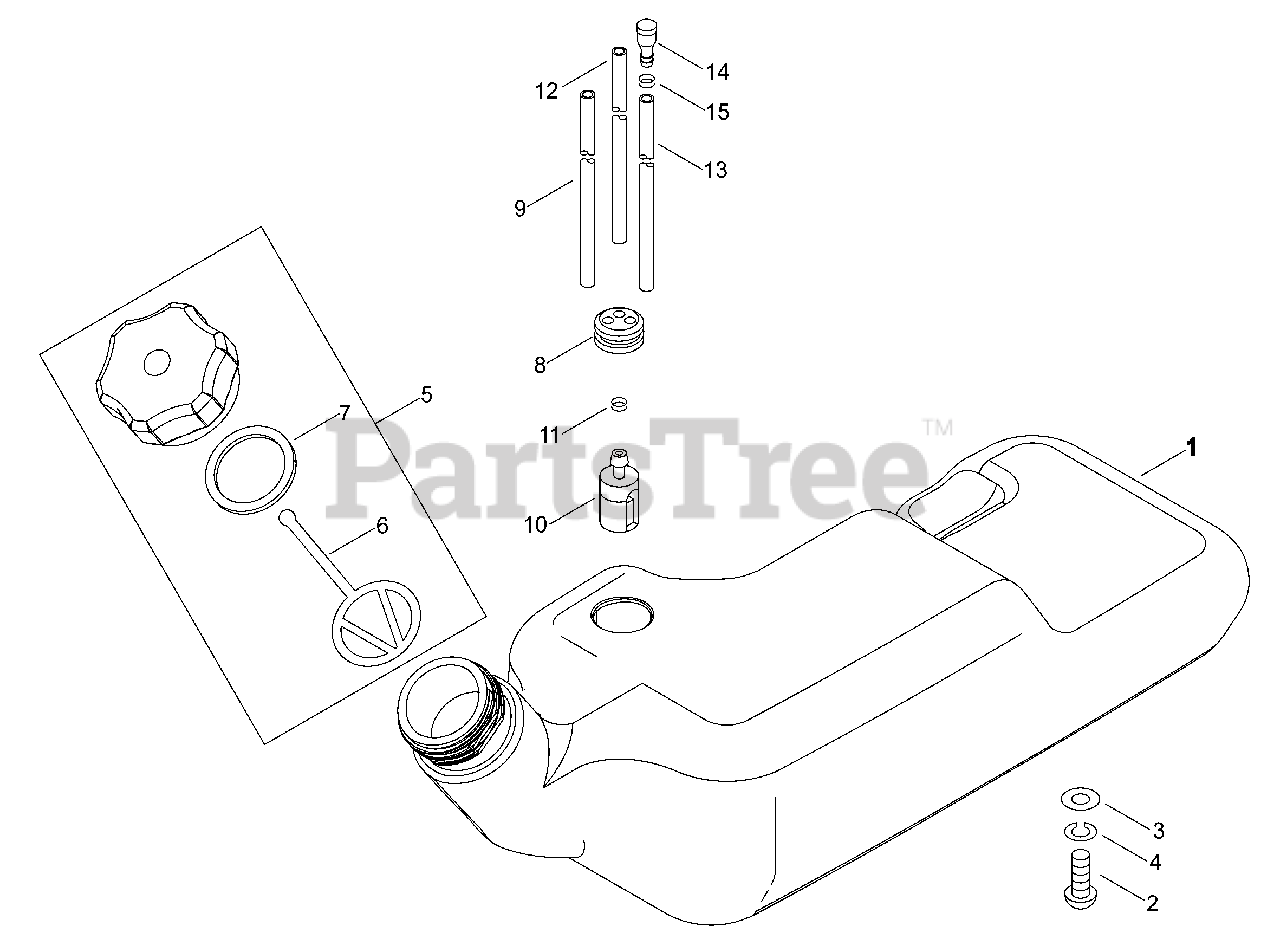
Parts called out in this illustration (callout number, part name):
1	TANK, FUEL
2	SCREW 6×14
3	WASHER 6.5×18×1.6
4	WASHER, SPRING 6
5	CAP ASSY, FUEL
6	+CONNECTOR, CAP L= 100 MM
7	+GASKET, FUEL CAP
8	GROMMET, FUEL
9	PIPE, FUEL 3×6×280 MM
10	FILTER, FUEL
11	CLIP Ø6.5 MM
12	PIPE, FUEL RETURN 3×6×145
13	PIPE, FUEL 3×6×110
14	VENT ASSY
15	CLIP, TUBE
